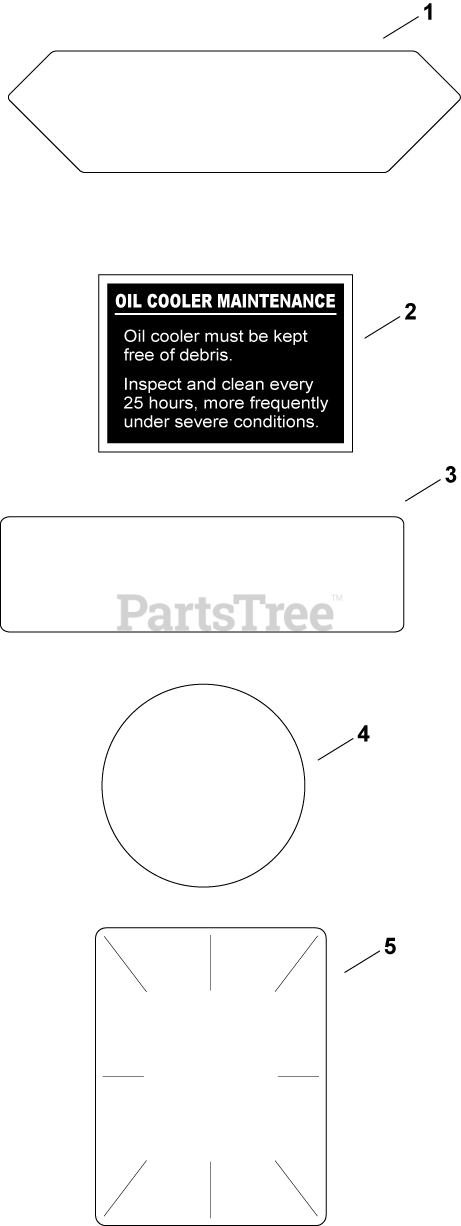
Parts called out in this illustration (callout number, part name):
1	DECAL, AIR FILTER COVER - DISC.
2	DECAL, OIL COOLER - (#DSC)
3	DECAL, 25 HP
4	LABEL, (ROUND KOHLER GOLD)-USE 24 113 18
5	DECAL, CLEAR LAMINATE USE 25 113 70-S
